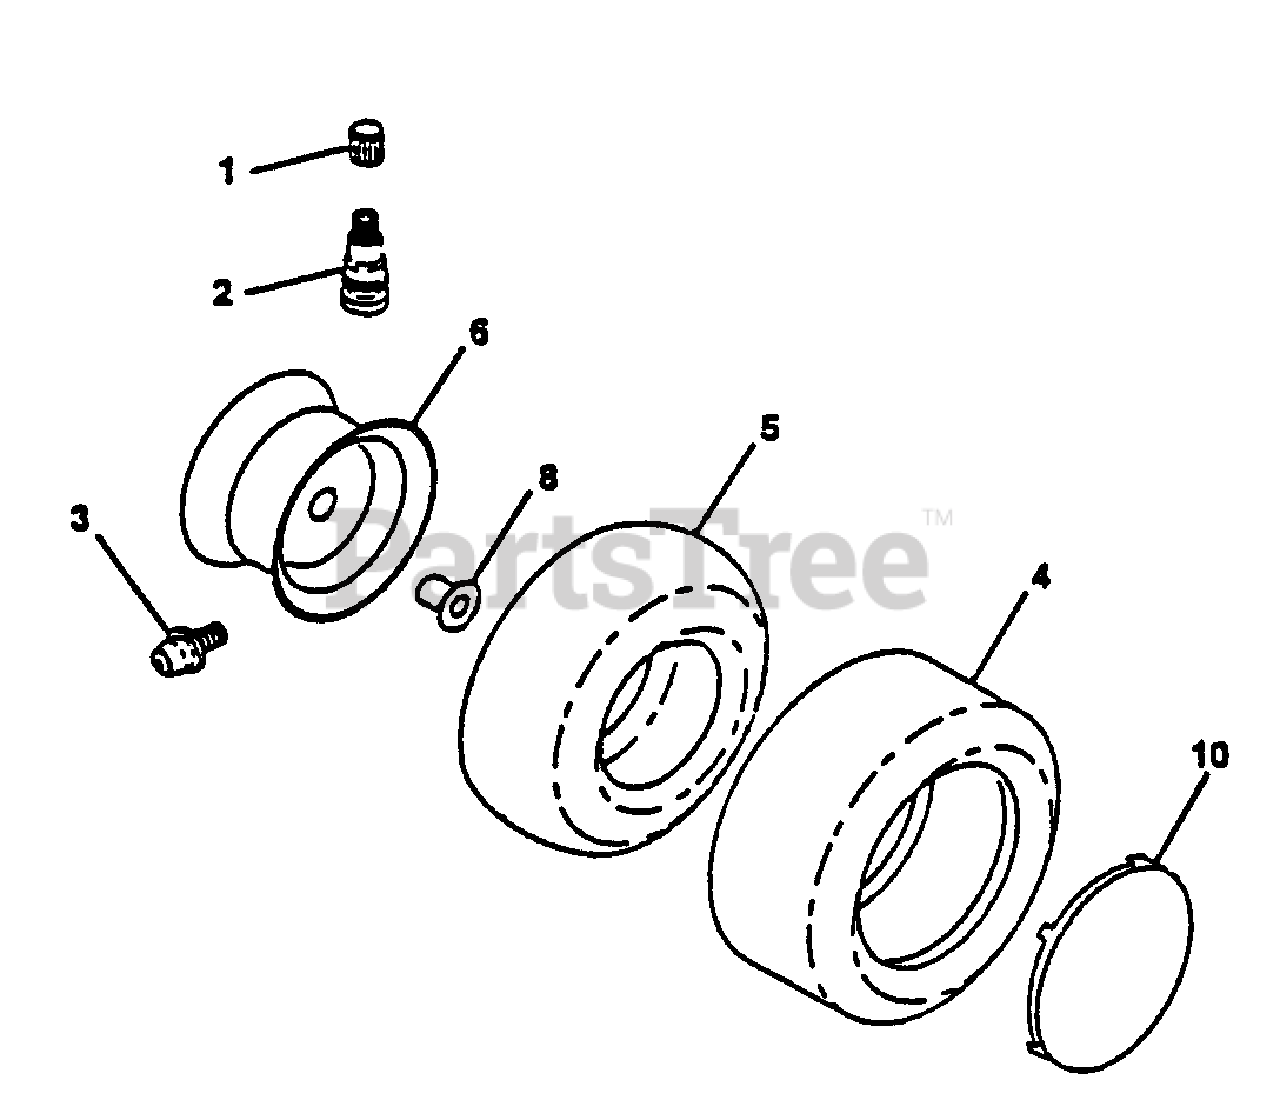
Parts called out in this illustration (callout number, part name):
1	Cap Valve Tire
2	Stem Valve
3	Fitting Grease
4	Tire F Ts 15 X 6 0 - 6 Service
4	Tire R Is 20x10 -8C Service
5	Tube Front
5	Tube Rear
6	Rim Asm 8" rear White Service
6	Rim Asm Front 6"
8	Bearing Flange
10	Cover Wheel 6" white
10	Cover Wheel 8" white
